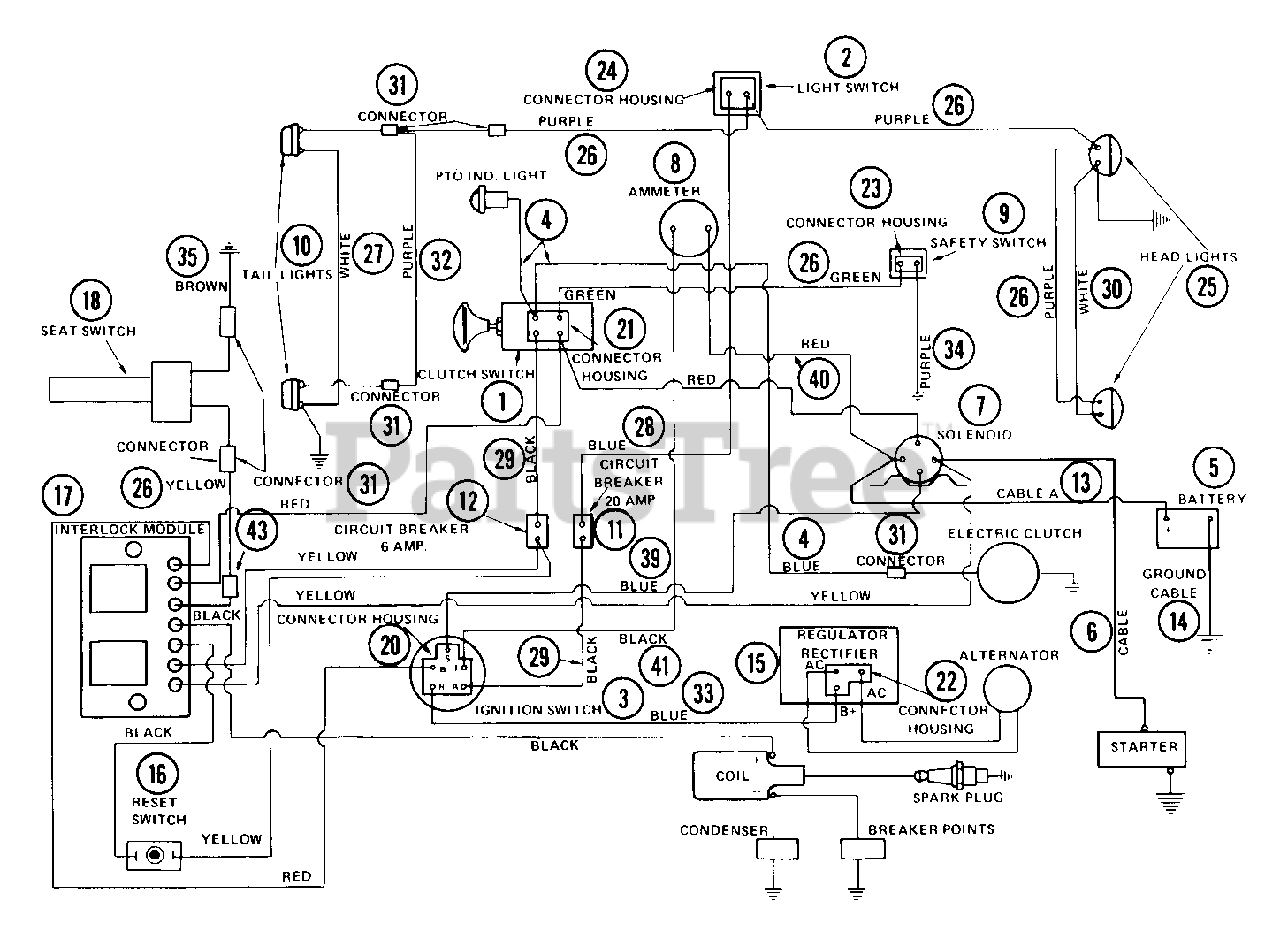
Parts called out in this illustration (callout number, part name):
1	CLUTCH SWITCH
2	LIGHT SWITCH
3	IGNITION SWITCH
4	P.T.O. INDICATOR & WIRE
5	BATTERY
6	GROUND CABLE .31X22.00X.31
7	SOLENOID
8	AMMETER
9	SAFETY SWITCH
10	TAIL LIGHT
11	CIRCUIT BREAKER
12	CIRCUIT BREAKER
14	GROUND CABLE
17	INTERLOCK MODULE KIT
18	SWITCH SEAT
20	CONNECTOR HOUSING
21	CONNECTOR
22	CONNECTOR
23	CONNECTOR
24	CONNECTOR
25	HEAD LIGHT
26	WIRE HARNESS
27	WIRE
27	GROUND FOR TAIL LITES
28	WIRE
28	BRAKE TO LITE SWITCH
29	WIRE
30	WIRE
31	WIRE CONNECTOR
32	WIRE
33	WIRE
34	WIRE
35	WIRE GROUND
39	WIRE
40	WIRE
41	WIRE
43	CONNECTOR
43	PTO INDICATOR BULB
